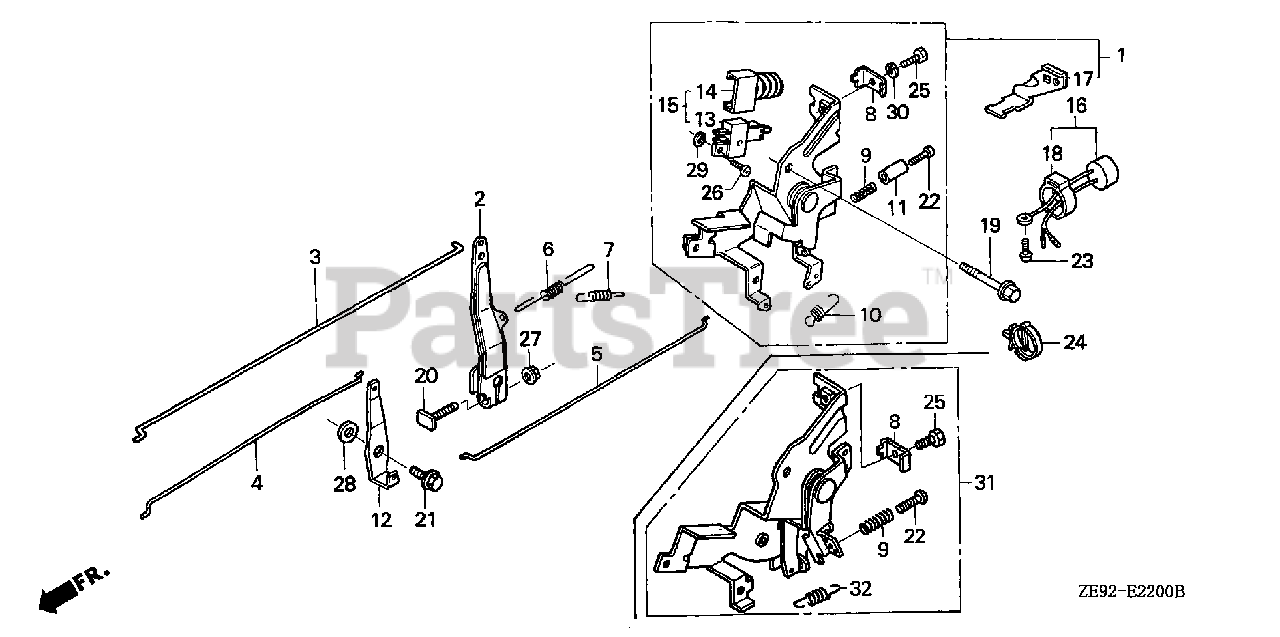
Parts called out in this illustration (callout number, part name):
1	CONTROL ASSY.
2	ARM, GOVERNOR
3	ROD, GOVERNOR
4	ROD, CHOKE
5	ROD, JOINT
6	SPRING, GOVERNOR
7	SPRING, GOVERNOR PRIMARY
8	HOLDER, CABLE
9	SPRING, CONTROL ADJUSTING
10	SPRING, CABLE RETURN
12	LEVER, CHOKE JOINT
13	SWITCH ASSY., ENGINE
14	COVER, SWITCH
15	SWITCH ASSY., ENGINE STOP
19	BOLT, FLANGE (6X12) (CT200)
20	BOLT, GOVERNOR ARM
21	BOLT, FLANGE (6MM)
22	SCREW, PAN (5X20)
25	BOLT, RECESSED (5X14)
26	SCREW, PAN (4X14)
27	NUT, FLANGE (6MM)
28	WASHER, PLAIN (6MM)
29	WASHER, SPRING (4MM)
